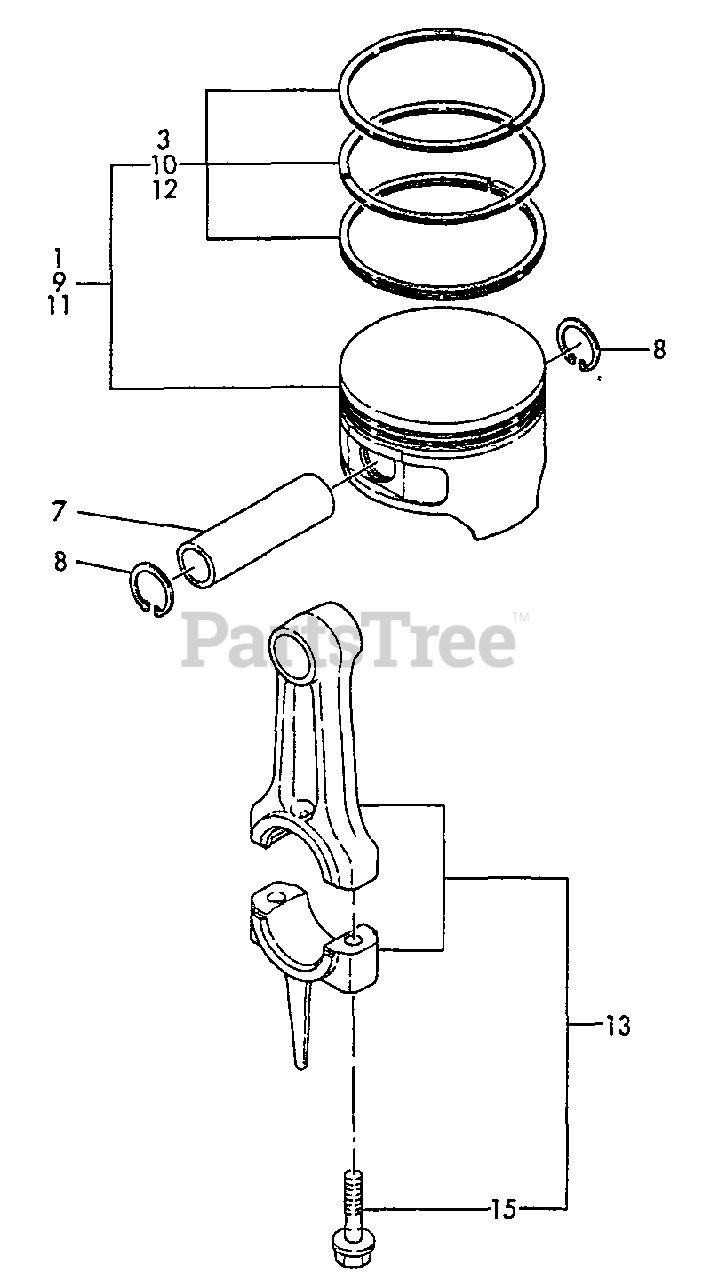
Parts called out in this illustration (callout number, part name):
1	PISTON ASSY
3	PISTON RING ASSY
7	PIN, PISTON
8	RING, RETAINING - 19
9	PISTON ASSY O.S.= 0.25
10	RING ASSY O.S.= 0.25
11	PISTON ASSY O.S.= 0.5
12	RING ASSY O.S.= 0.5
13	CONNECTING ROD ASSY
15	BOLT, ROD
